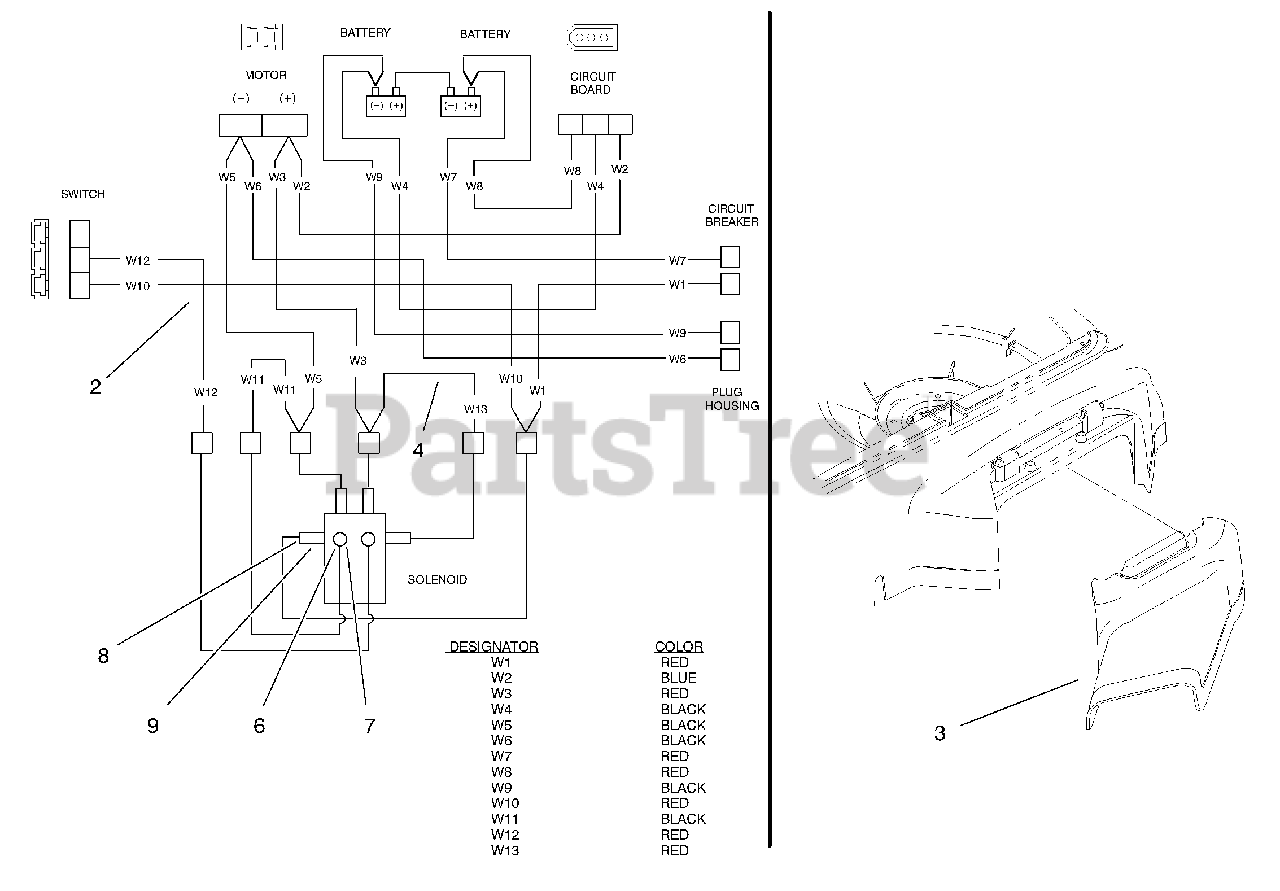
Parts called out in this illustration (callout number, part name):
2	Harness-Wire (Incl. W1-W12)
3	Chute-Side Discharge
4	Harness-Wire (Incl. W13)
7	Washer-Lock
8	Nut-Jam
9	Washer-Lock
